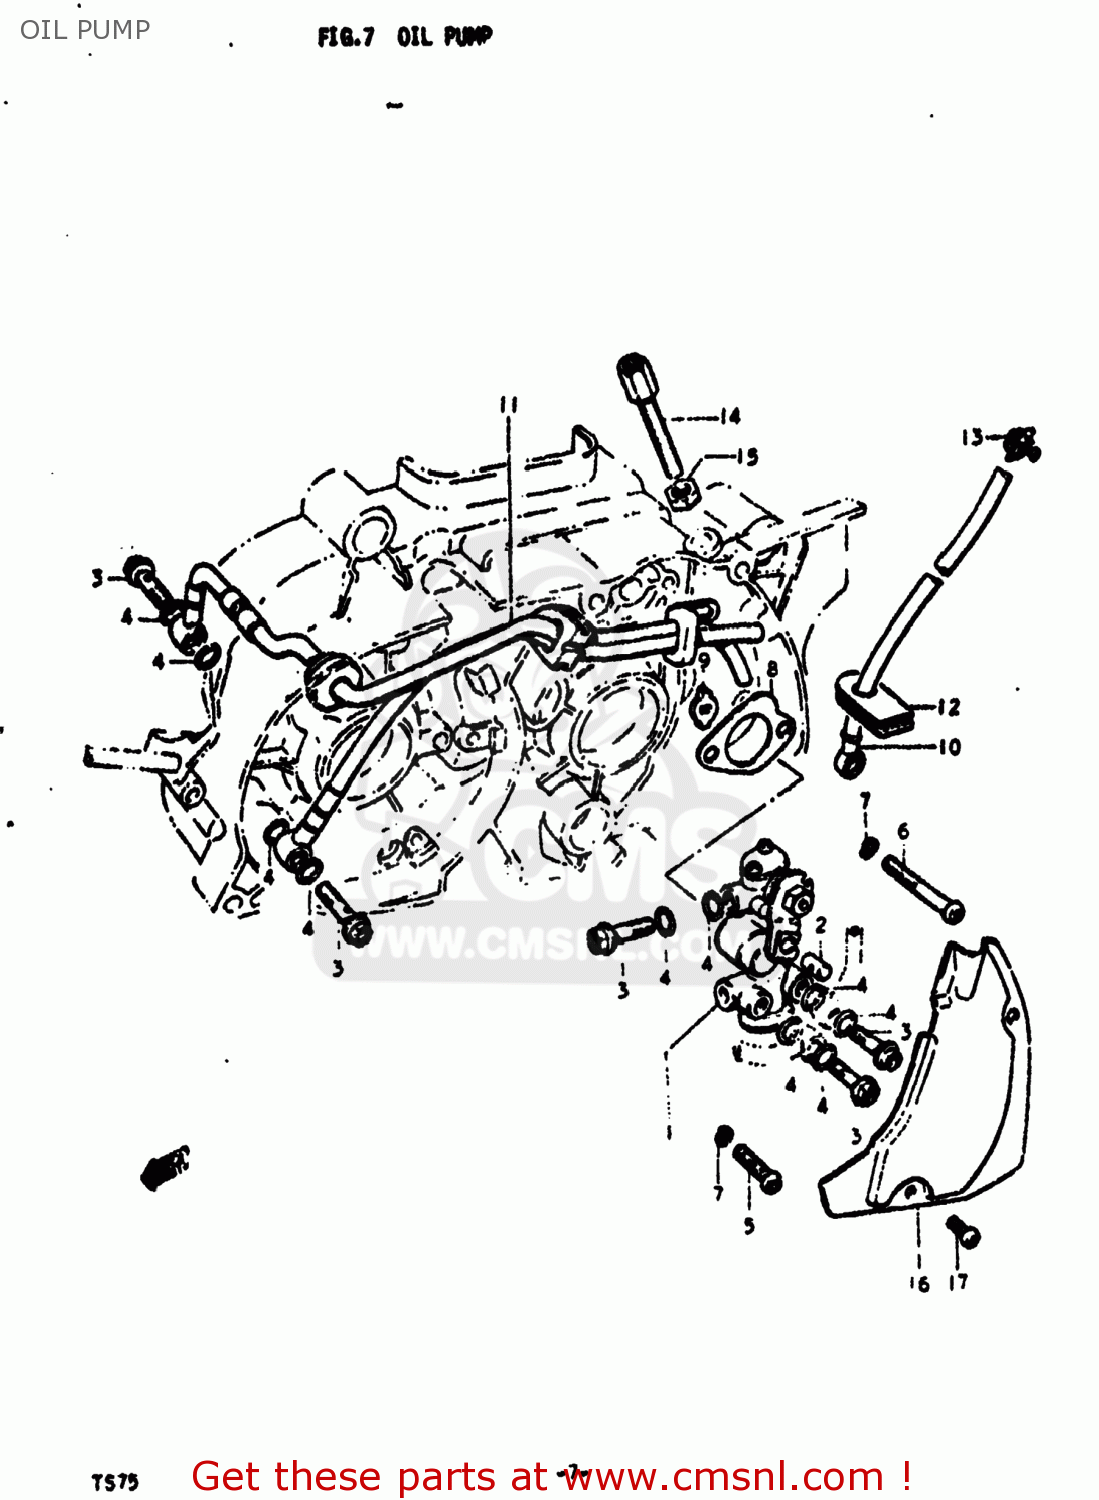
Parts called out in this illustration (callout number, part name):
1	PUMP ASSY,OIL
2	TERMINAL,CABLE
3	UNION BOLT
4	GASKET(6.2X11X1).2 (NAS)
5	SCREW
6	SCREW
7	LOCK WASHER
8	GASKET,OIL PUMP (MCA)
9	PIECE,OIL PUMP DRIVE
10	HOSE,OIL NO.1
11	HOSE,OIL NO.2
12	GROMMET
13	CLAMP
14	BOLT
15	NUT
16	CAP,OIL PUMP INSPECTION
17	SCREW
